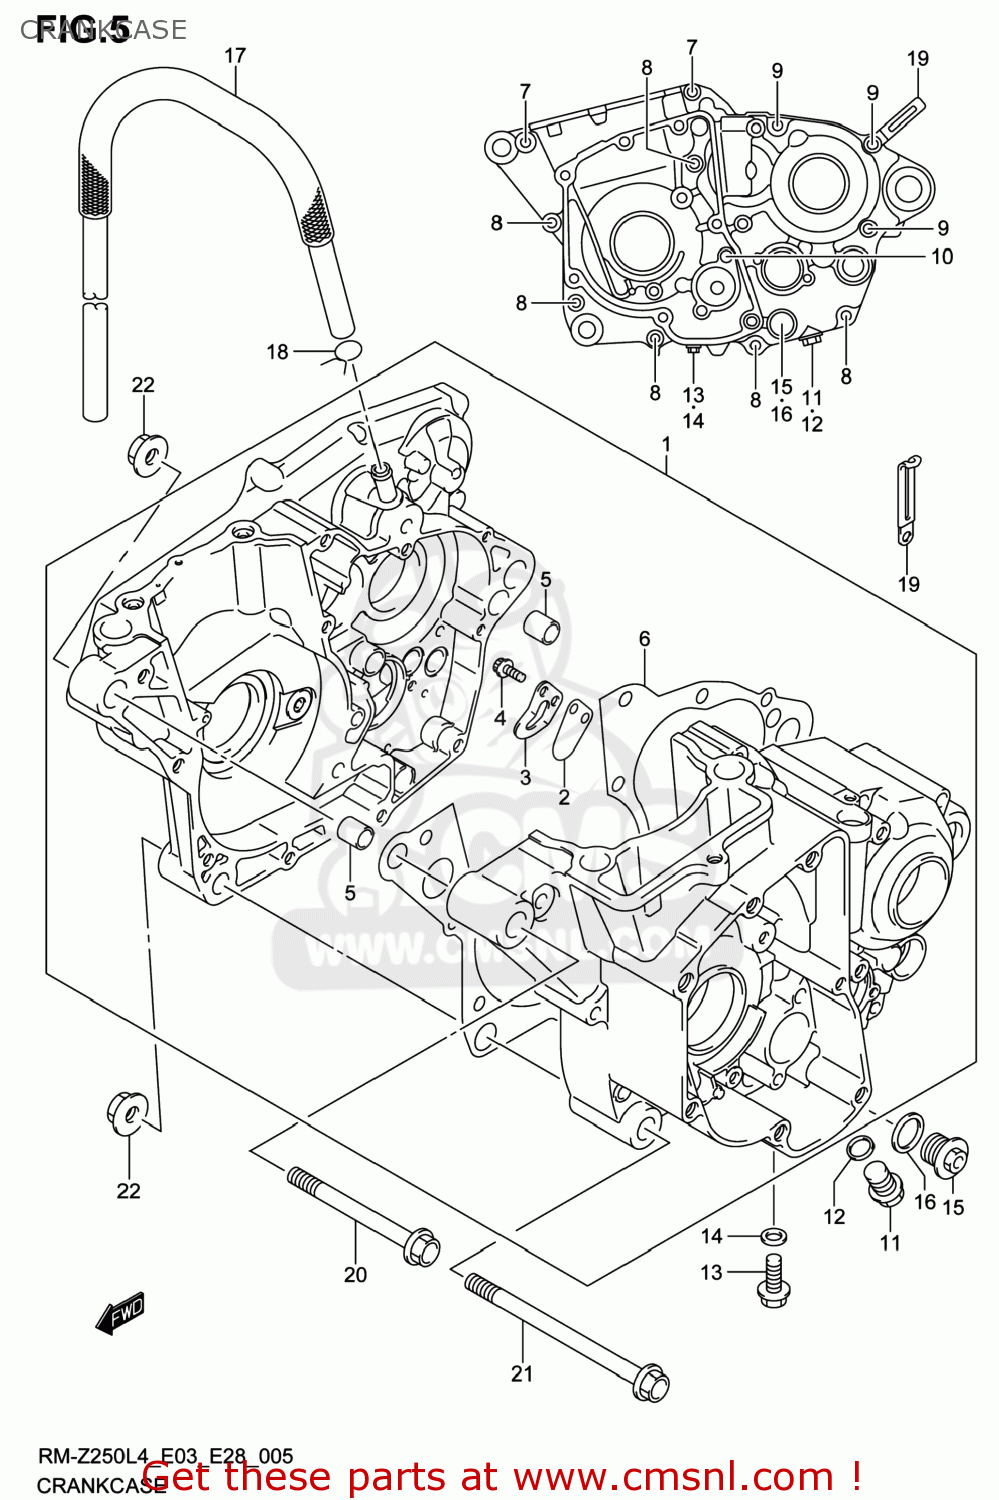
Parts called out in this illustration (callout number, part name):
1	CRANKCASE ASSY
2	VALVE,CRANKCASE REED
3	STOPPER,CRANKCASE REED VALVE
4	BOLT
5	PIN(10.4X13X18)
6	GASKET,CRANKCASE (NAS)
7	BOLT
8	BOLT
9	BOLT
10	BOLT
11	PLUG,12X20
12	GASKET(12.1X16.2X3.7) (NAS)
13	BOLT(8X20)
14	GASKET(7.8X13.5X1.2) (NAS)
15	CAP,ENG OIL STRAINER
16	GASKET(16X22X2) (NAS)
17	HOSE,BREATHER
18	CLIP
19	CLAMP(L:45)
20	BOLT(10X80)
21	BOLT(10X120)
22	NUT
